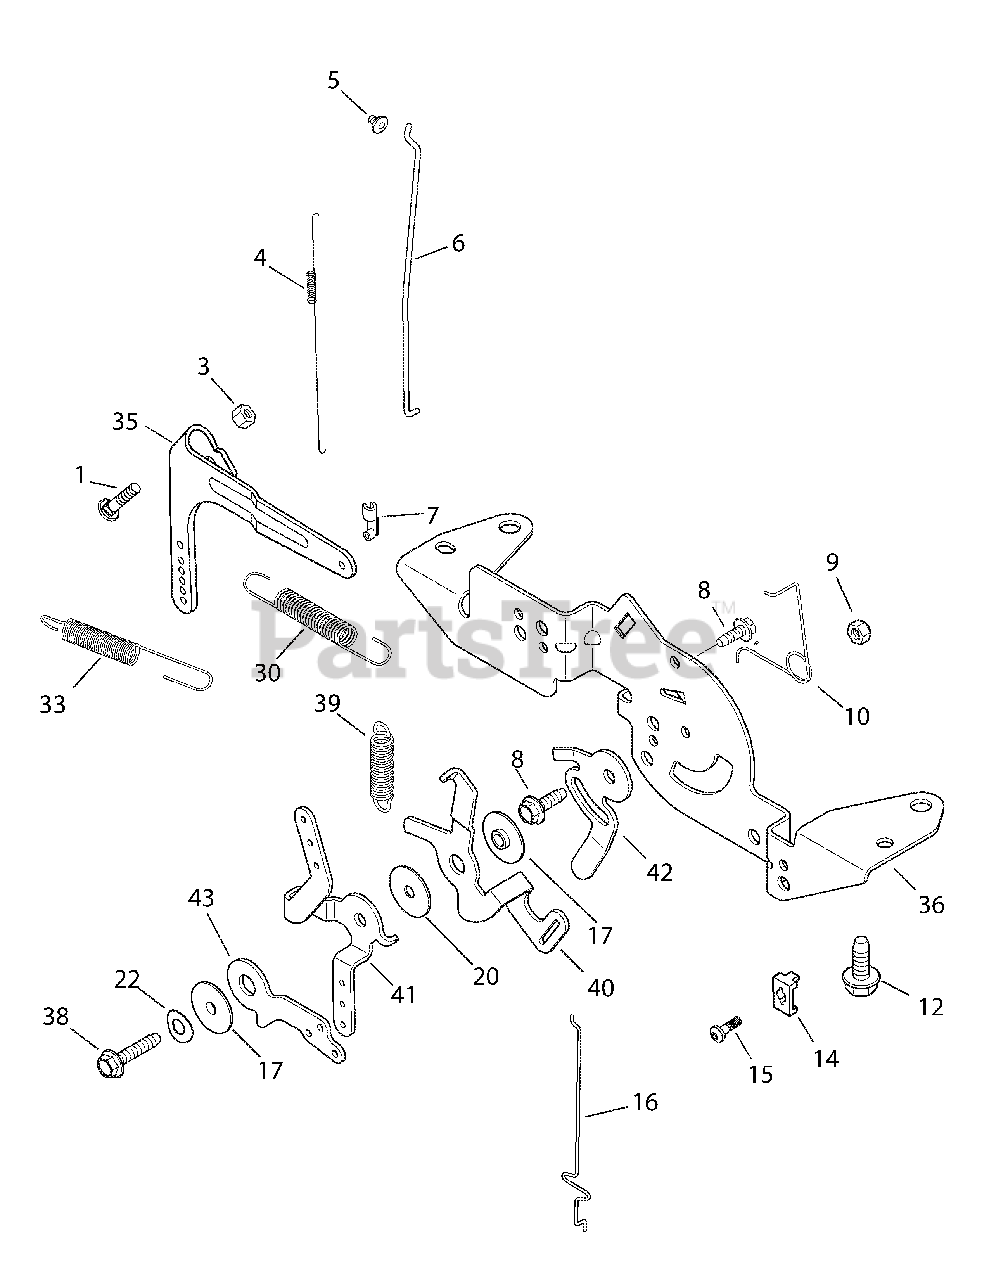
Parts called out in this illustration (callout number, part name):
1	Rd. Hd. Sq. Neck Bolt, M6 X 1.0 X 25
3	Flg. Nut, M6 X 1.0
4	Linkage Spring
5	Linkage Retaining Bushing
6	Throttle Linkage
7	Throttle Linkage Bushing
8	Flg. Thd. Frm. Screw, M5 X 0.8 X 16
9	Lock Nut, M5 X .8
10	Choke Return Spring
12	Flg. Thd. Frm. Screw, M6 X 1.0 X 16
14	Cable Clamp
15	Lbd. Thd. Frm. Screw, M5 X 0.8 X 16
16	Choke Linkage
17	Control Assembly Spacer
20	Flat Washer. 5.5mm
22	Spring Washer, 1/4
30	Governor Spring
33	Governor Spring
35	Governor Lever
36	Control Bracket
38	Thd. Frm. Screw, M5 X 0.8 X 25mm
39	Speed Control Spring
40	Governor Spring Lever
41	Speed Control Lever
42	Speed Setting Lever
